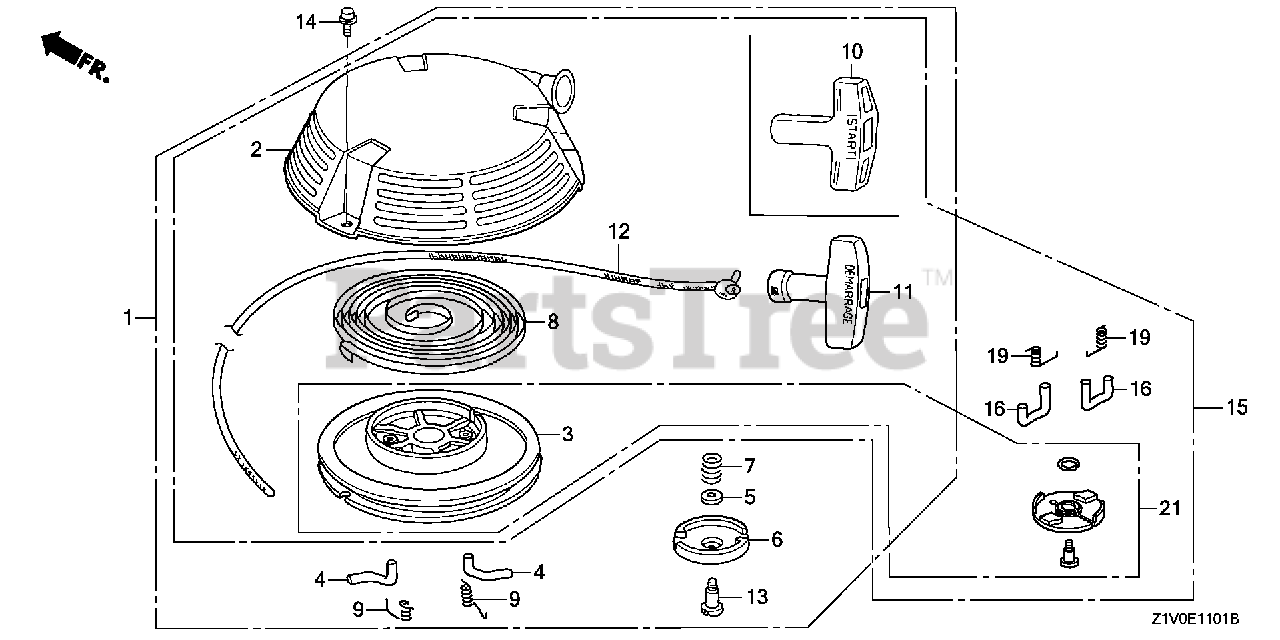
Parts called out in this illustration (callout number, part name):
1	STARTER ASSY., RECOIL *NH1* (BLACK)
2	CASE, RECOIL STARTER *NH1* (BLACK)
3	REEL, RECOIL STARTER (BLACK)
4	RATCHET, STARTER
5	PLATE, FRICTION
6	GUIDE, RATCHET
7	SPRING, FRICTION
8	SPRING, RECOIL STARTER
9	SPRING, RETURN
11	KNOB, RECOIL STARTER
12	ROPE, RECOIL STARTER
13	SCREW, SETTING
14	BOLT, FLANGE (6X8)
